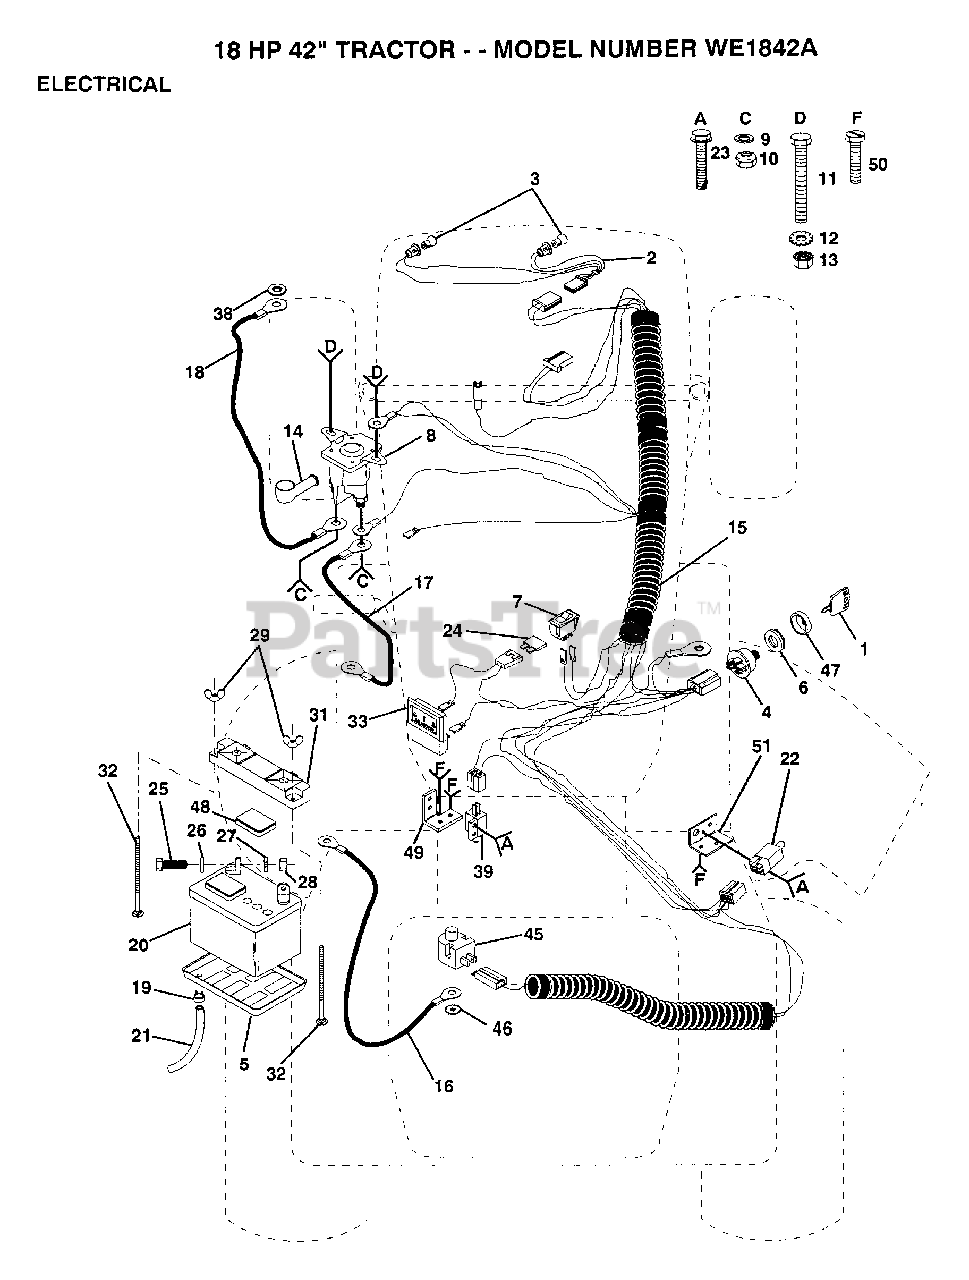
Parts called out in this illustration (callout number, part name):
1	KEY
2	"HARNESS,LIGHT SOC"
3	HEADLAMP BULB
5	"TRAY T, BATTERY"
6	NUT IGNITION
7	SWITCH LT
10	NUT
11	BOLT
13	NUT
15	HARNESS.IGN
16	"CABLE T, BATTERY"
17	HOSE CLAMP T
18	CABLE T
19	HOSE CLAMP T
21	"DRAIN TU T, BATT"
22	SWITCH-INTER. GT
23	SCREW
24	FUSE HYT
25	BOLT LT
26	WASHER
27	LOCKWASHER
32	BOLT
38	LOCKWASHER
39	SWITCH INTERLOCKT
45	SWITCH SEAT
46	LOCKWASHER
48	"CAP,BATTERY "
49	SWITCH BRACKET
50	SCREW
51	BRACKET LT
